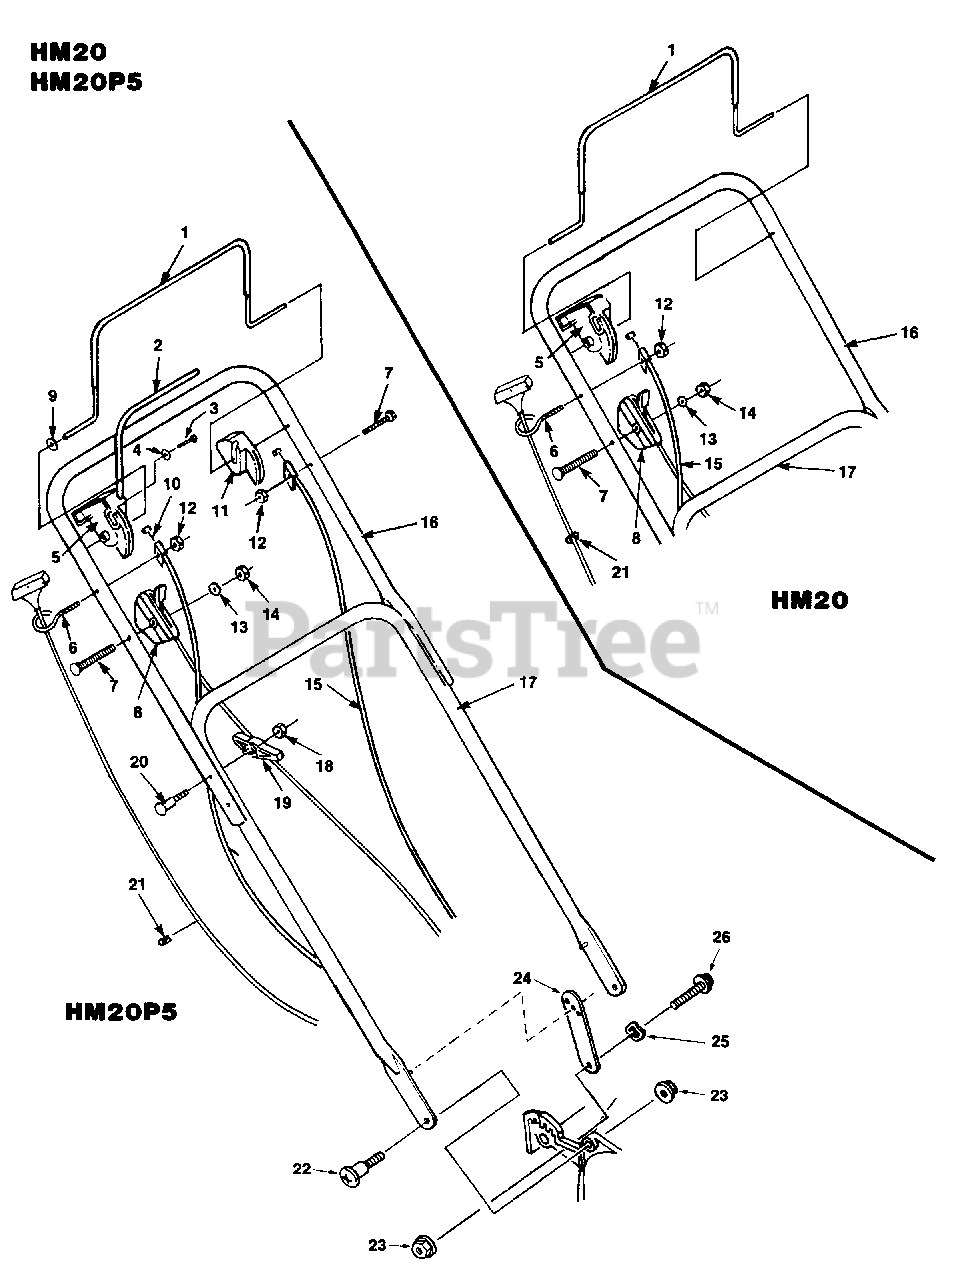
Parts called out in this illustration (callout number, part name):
1	BAIL- Brake control
2	TRACTION LEVER
3	SCREW - Hex #10-16
6	Eyebolt - starter rope 1/4-20
7	Screw - truss hd 1/4-20 x 1-3/4
8	THROTTLE CONTROL
9	FLAT WASHER(HSD'S) TBO
10	Pulley - drive
11	ACTUATOR- L.H.
12	Nut - hex 1/4-20 lock
13	WASHER- External tooth (1/4")
14	NUT - Hex 1/4-20
17	Handle - lower
18	NUT TBO
19	HANDLE KNOB-TBO
21	STOP - Rope
22	BOLT- Handle mtg.
23	HEX WASHER NUT-TBO
24	HANDLE SUPPORT
